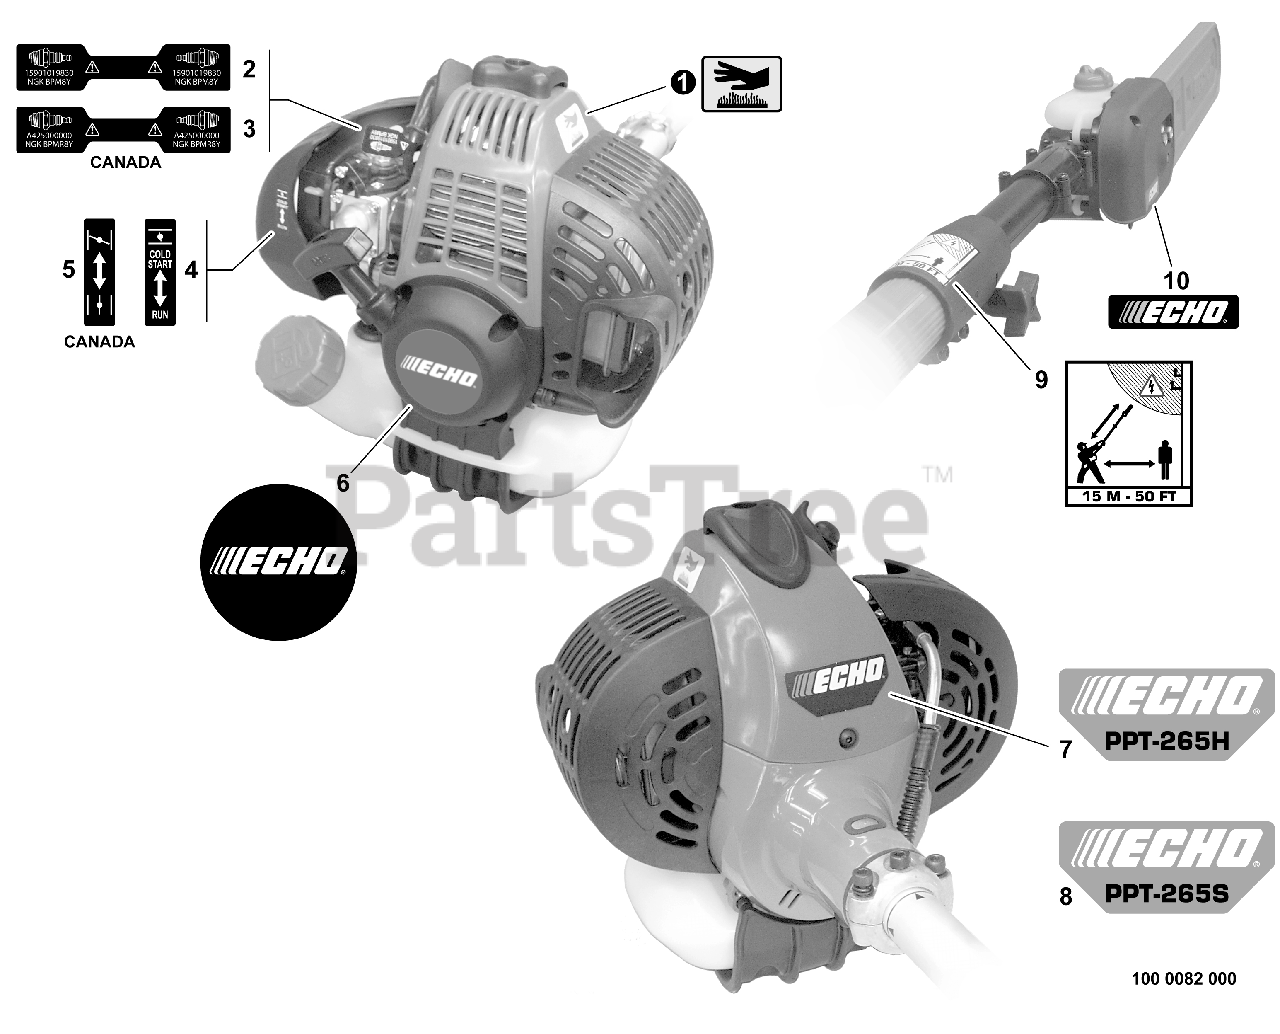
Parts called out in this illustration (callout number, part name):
1	LABEL - HOT SURFACE
2	LABEL - SPARK PLUG -- BPM-8Y
3	LABEL - SPARK PLUG -- BPMR-8Y
4	LABEL - CHOKE
5	LABEL - CHOKE
6	LABEL - ECHO
7	LABEL - MODEL PPT-265S
8	LABEL - MODEL PPT-265H
9	LABEL - WARNING
10	LABEL - ECHO
